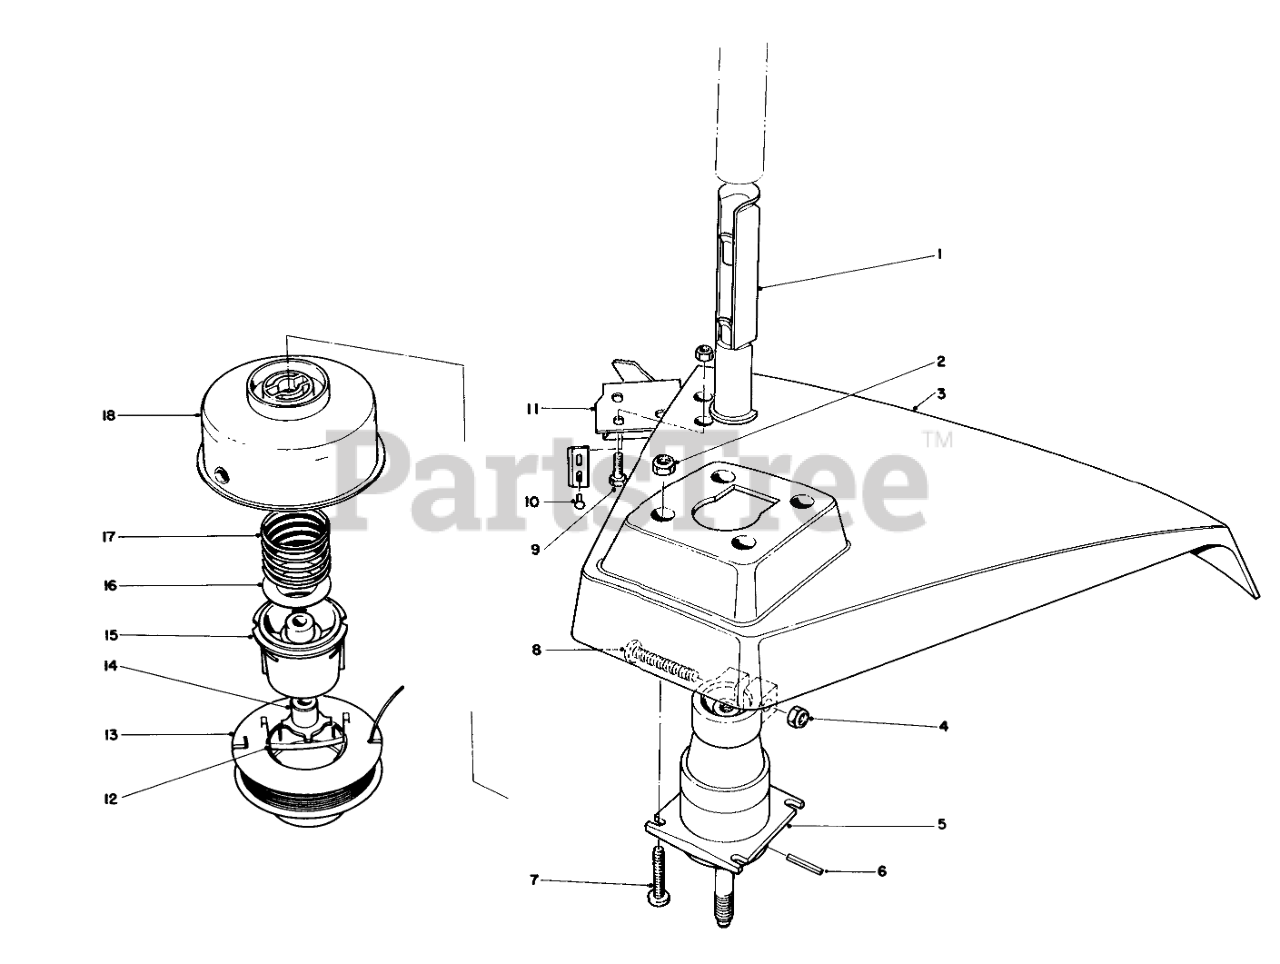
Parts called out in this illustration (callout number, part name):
1	Insert-Pole End
2	NUT-LOCK, NI
3	Shield
4	NUT-LOCK, NI
5	Bearing Housing Assembly
6	COIL PIN
7	SCREW-PPH
8	Screw-Pan Head Machine
9	SCREW-HWH
10	RIVET-BLIND
11	Knife Blade Assembly (Incl. Ref. #10)
12	SADDLE-SPOOL CAP
13	Prewound Spool (.080)
14	DRIVER
15	SPOOL CORE
16	Washer
17	SPRING COMPRESSION
18	DRUM/EYELET
